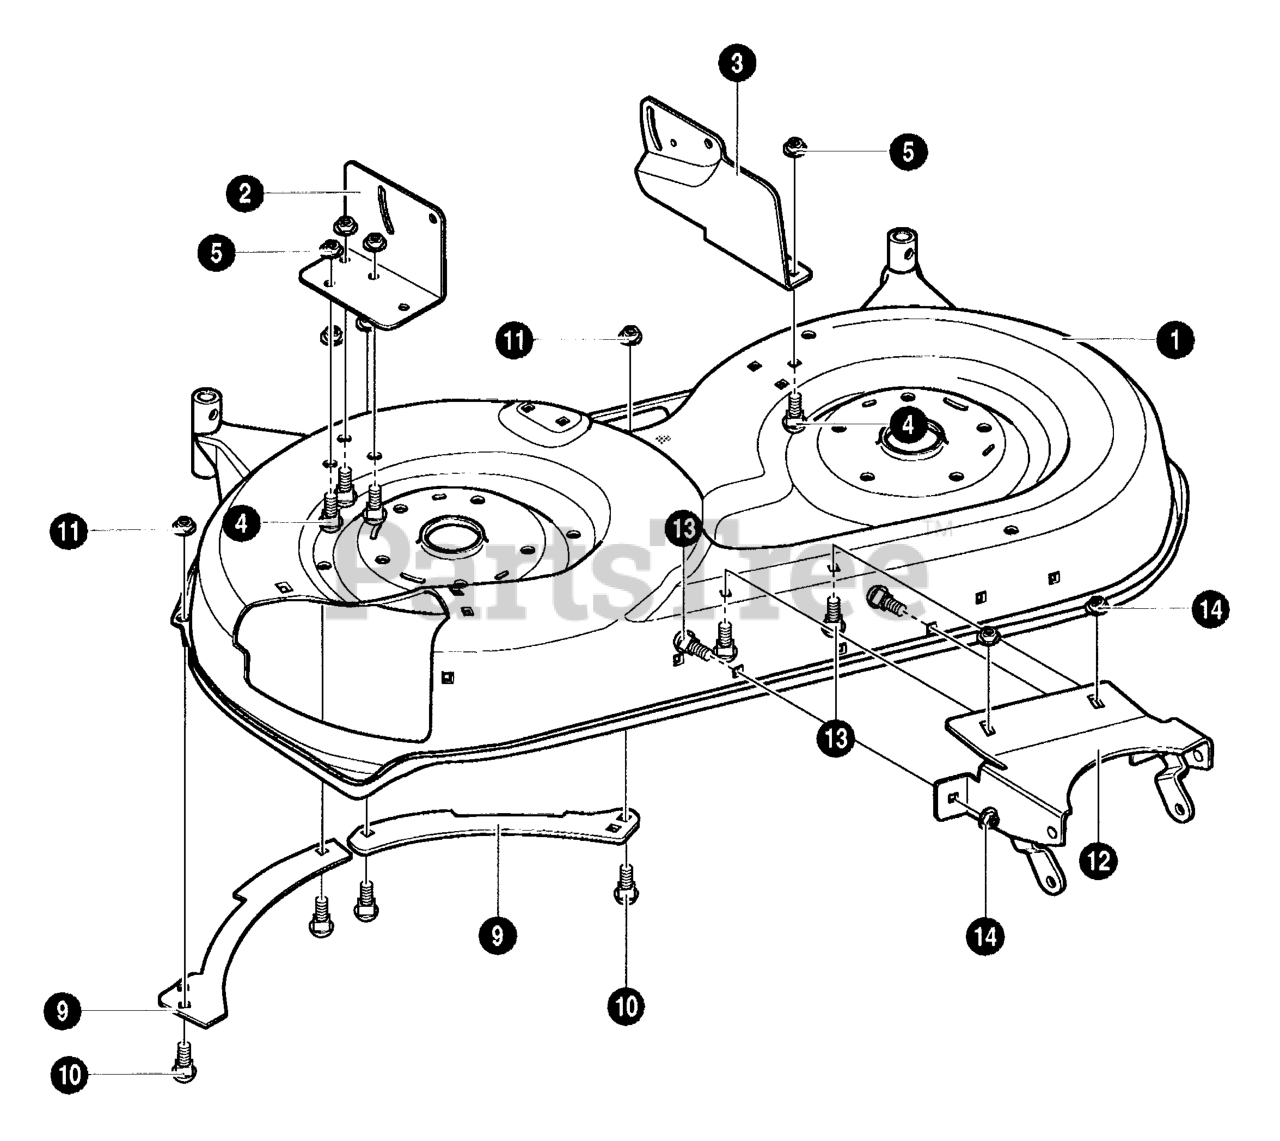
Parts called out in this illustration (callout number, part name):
1	ASSY BLD HSING 42"
2	BRACKET, DECK RH
3	BRACKET, DECK LH
4	BOLT, 5/16- 18X.63
5	NUT, 5/16- 18
9	TOEGUARD, FLANGE
10	BOLT, 5/16- 18X.63
11	NUT, 5/16- 18
12	ASSY FRONT BRACKET ROLLER
13	BOLT, 5/16- 18X.63
14	NUT, 5/16- 18
